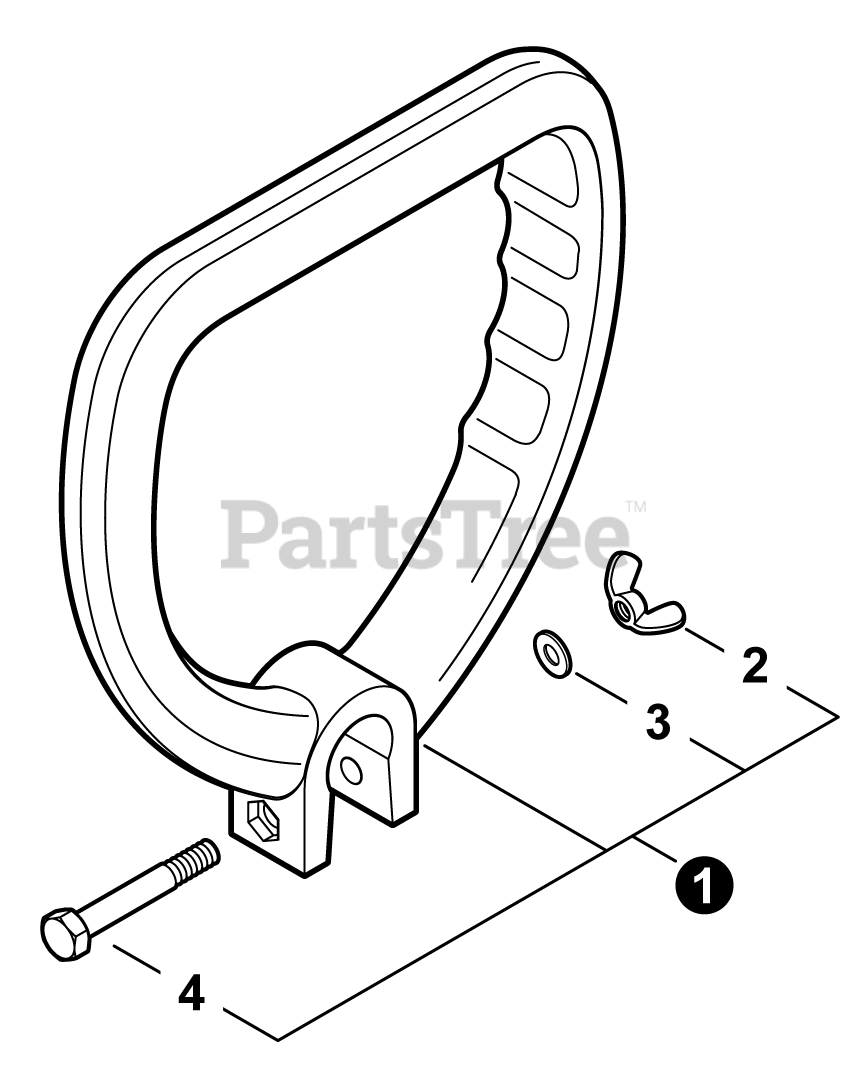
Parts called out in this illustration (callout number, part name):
1	HANDLE ASSY, FRONT
2	NUT, WING 1/4"-20
3	WASHER 6.5x11.5x0.8
4	BOLT 1/4"-20x1-3/4"
